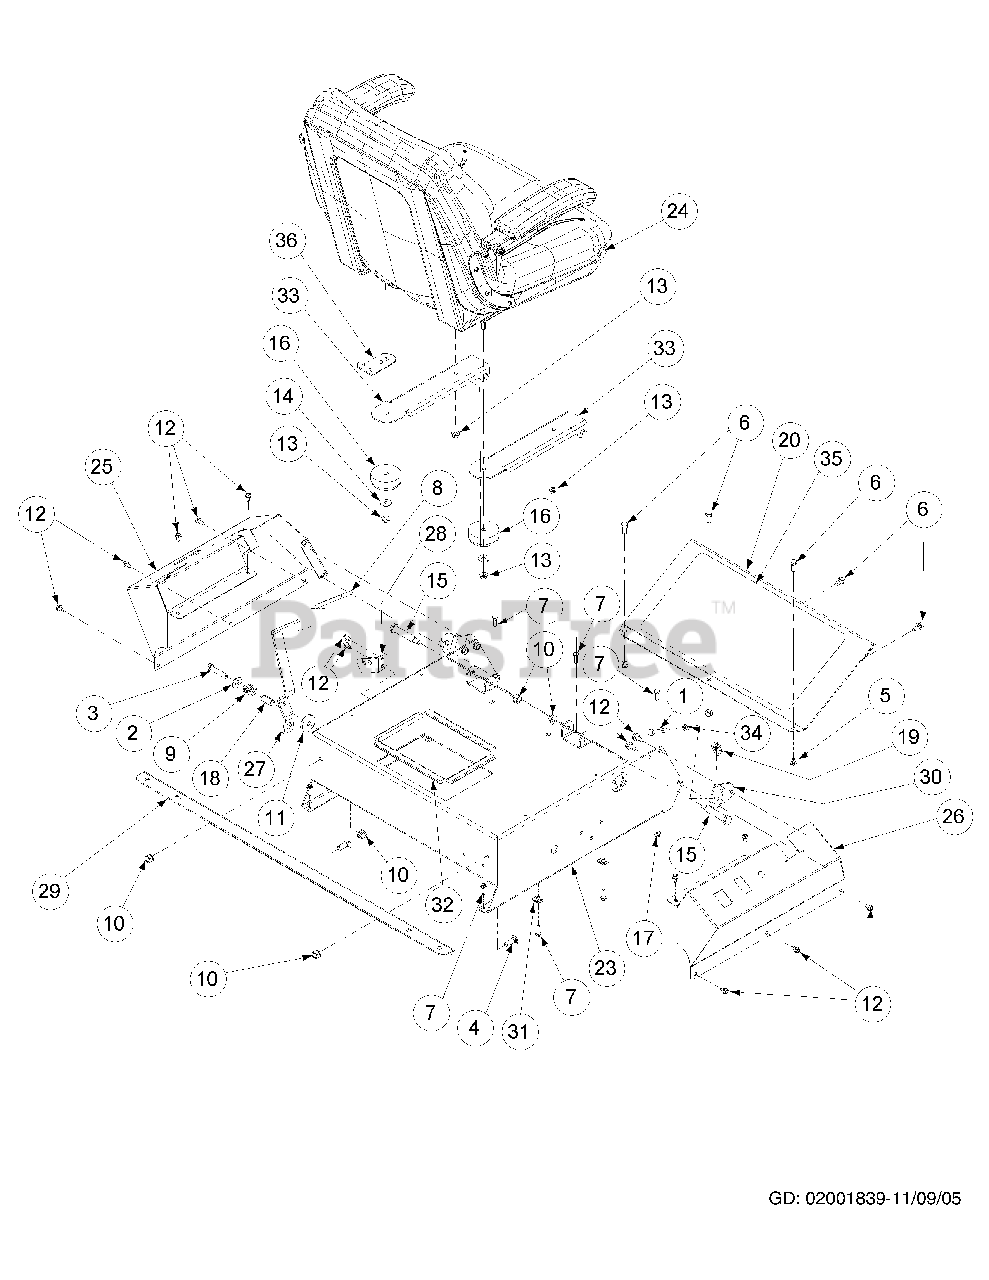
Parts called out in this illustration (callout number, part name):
1	Hex Cap Screw, 5/16-18 x 1-1/2
2	Idler Washer
3	Capscrew, 3/8-16 x 1-3/4
4	Carriage Bolt, 3/8-16
5	Nylock Nut, 5/16-18
6	Self Tapping Screw, 5/16-18 x 3/4
7	Self Tapping Screw, 1/4-20 x .75
8	Parking Brake Grip
9	Spring, .85 OD x 1 Lg
10	Hex Nut, 3/8-16 Flange Lock
11	Flat Washer, 1.25 x .411 x .100
12	Screw, 1/4-20 x 1/2
13	Hex Nut, 5/16-18 Flange Lock
14	Washer, .325 x .930 x .045
15	Shoulder Screw, 3/8-16, .5 x 2.345
16	Groment, 2.5 OD x 1.0 Lg
17	Hex Nut, 1/4-20 Flange Lock
18	Spacer, .375 x .50 x 1.02
19	U-Nut, 5/16-18
20	Foot Rest Bracket
23	Control Housing Weldment
25	Left Hand Control Console
26	Right Hand Control Console
27	Parking Brake Lever
28	Brake Cable Bracket
29	Front Tank Mounting Bracket
30	Lapbar Stop Bracket
31	U-Nut, 1/4-20
32	Battery Edge Trim
33	Seat Mounting Bracket
34	Hex Nut, 5/16-18
35	Abrasive Foot Pad
36	Seat Stop Bracket
